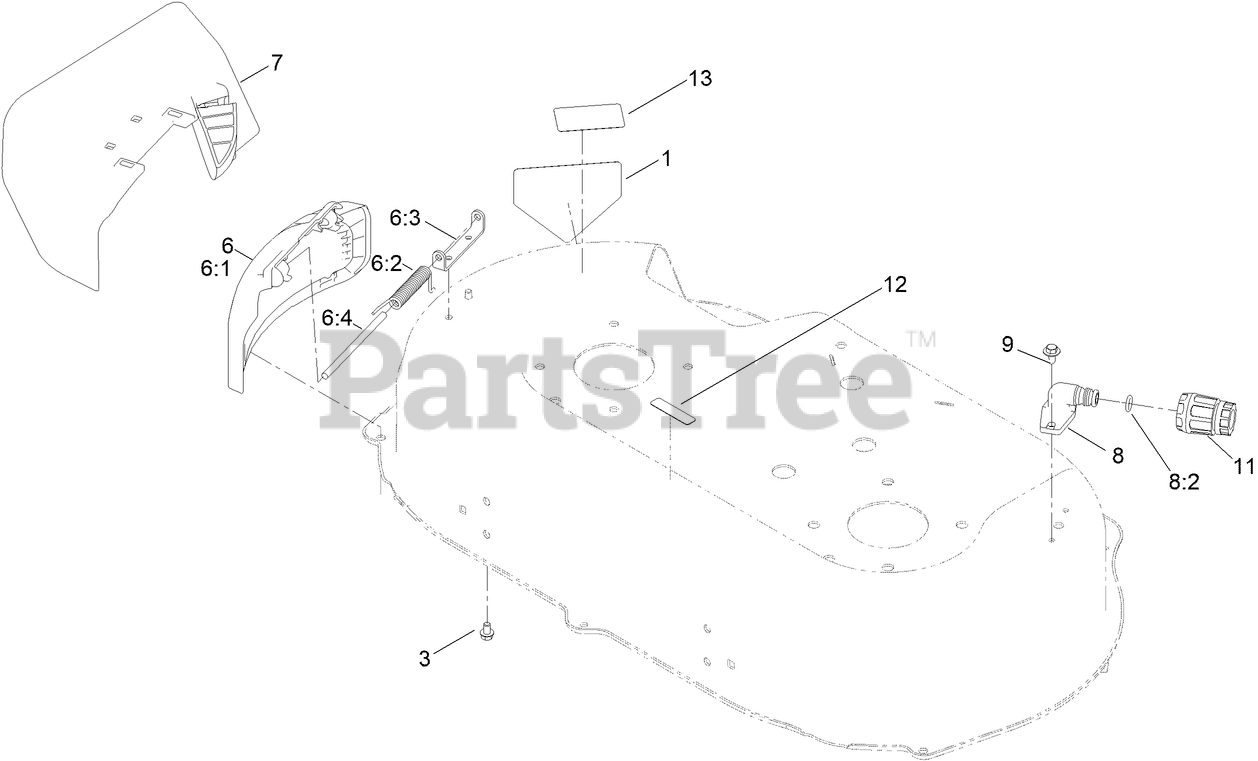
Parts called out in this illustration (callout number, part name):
1	DECAL-DANGER
6	SIDE DEFLECTOR SERVICE ASM
6:1	DEFLECTOR-SIDE
6:2	SPRING-TORSION, COVER
6:3	BRACKET-COVER
7	CHUTE-DISCHARGE, SIDE
8	FITTING-WASHOUT
8:2	O-RING
9	SCREW-HWH, THD ROLL
11	CONNECTOR-HOSE
12	DECAL-WARNING
13	DECAL-PLACEMENT, FOOT
